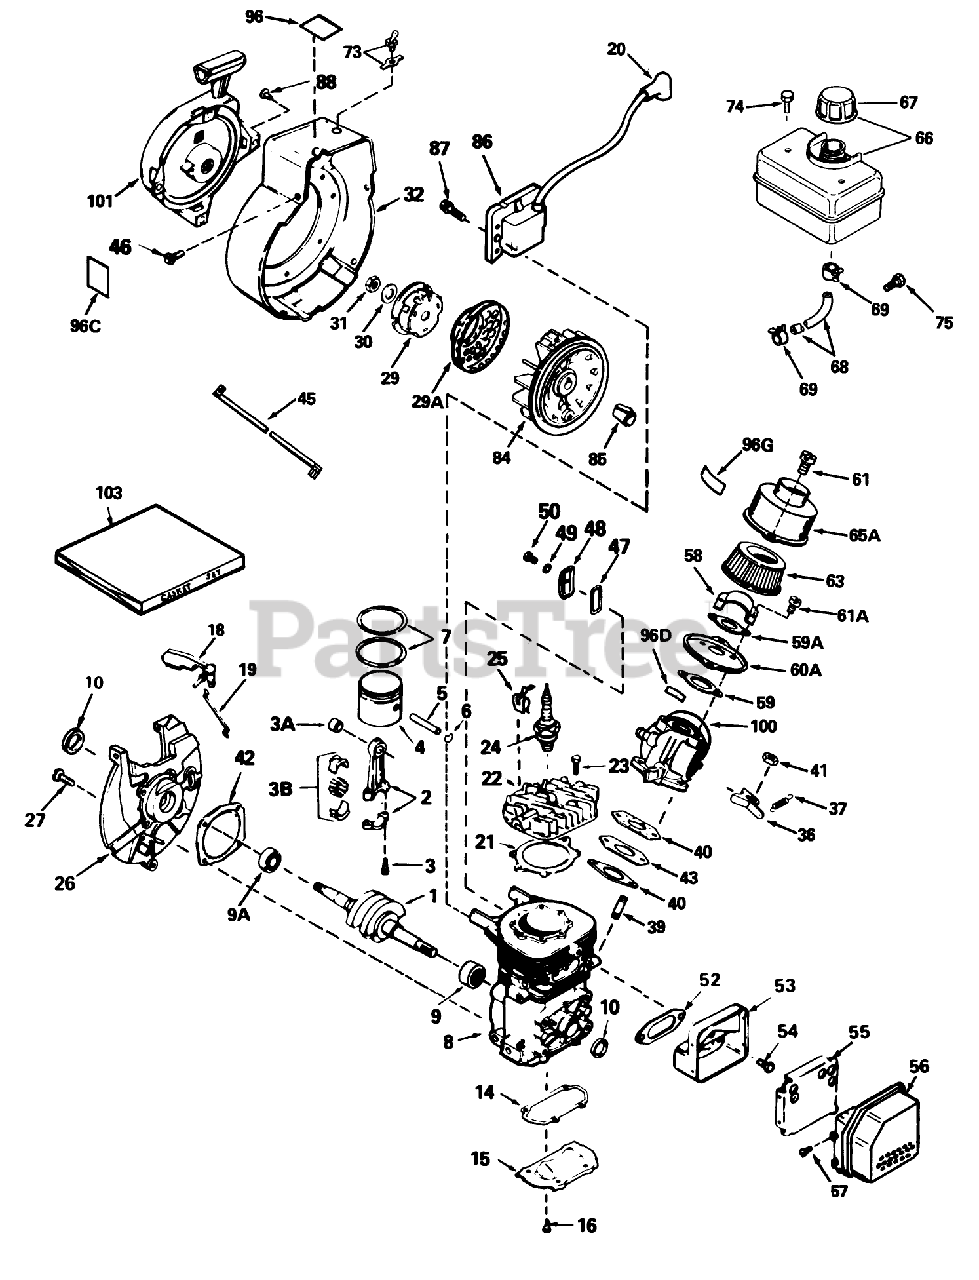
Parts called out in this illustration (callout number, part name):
1	Crankshaft
1	Screw
2	Rod Assy.-Connecting (Incl. Ref. #3, 3A 3B)
2	Retainer
3	Bolt-Rod, Connecting
3	Spring-Brake
3A	Bearing-Cartridge
3B	Needle Bearing and Liner Set (37 Needles)
4	Piston
4	Dog-Starter
5	Pin-Piston
5	Spring-Dog
6	Ring-Retaning
6	Pulley
7	Ring Set
7	Spring Keeper Assy
8	Cylinder Block Assy. (Order short block if replacement is required)
8	Housing Assy., Starter (Incl. Ref. #1)
9	Bearing-Cartridge
9	Rope-Starter (98 cut to length)
9A	Bearing-Ball
10	Seal-Oil
10	Handle-Starter
14	Cover
15	Plate-Cover
16	Screw (T-25, 10-24 x 1/2)
18	Vane-Air
19	Link-Governor
20	Cover-Spark Plug
21	Gasket, Head
22	Head-Cylinder
23	Screw (T-30, 1/4-20 x 3/4)
24	Spark Plug-Resistor (R C J 8Y)
26	Base Assy.-Blower Housing (Incl. Ref. #10)
27	Screw (T-30, 1/4-20 x 5/8)
29	Cup-Starter
29A	Screen, Air
30	Washer-Belleville
31	Nut-Flywheel
32	Housing-Blower
36	Lever-Adjusting, Rpm
37	Spring-Governor
39	Stud-Carburetor
40	Gasket-Carburetor
41	Locknut
42	Gasket, Shroud Base
43	Spacer
45	Wire-Ground
46	Screw-Hex, Hd.
47	Gasket-Cover
48	Comp. Release Cover
49	Washer
50	Screw (T-25, 10-24 x 1/2)
52	Gasket-Muffler
53	Base-Muffler
54	Screw (T-30, 1/4-20 x 5/8)
55	Baffle-Muffler
56	Cover Muffler
57	Screw
58	Baffle-Carburetor
59	Gasket
59A	Gasket
60A	Bracket
61	Screw
61A	Screw (10-32 x 1/2)
63	Element
65A	Cover-Air Cleaner
66	Tank Assembly-Fuel (Incl. Ref. #250 253)
67	Cap-Fuel
68	Line-Fuel
69	Clamp-Line, Fuel
73	Switch
74	Screw
75	Screw (1/4-15x7/8)
84	Flywheel
85	Blade (20 inch)
86	Solid State
87	Screw
88	Rivet-Pop (obtain locally)
96	Decal-Name
96C	Decal-Fuel Mixture
96D	Decal-Primer
96G	Decal-Air Cleaner
100	Carburetor Assembly (Incl. Ref. #40)
101	Starter-Rewind
